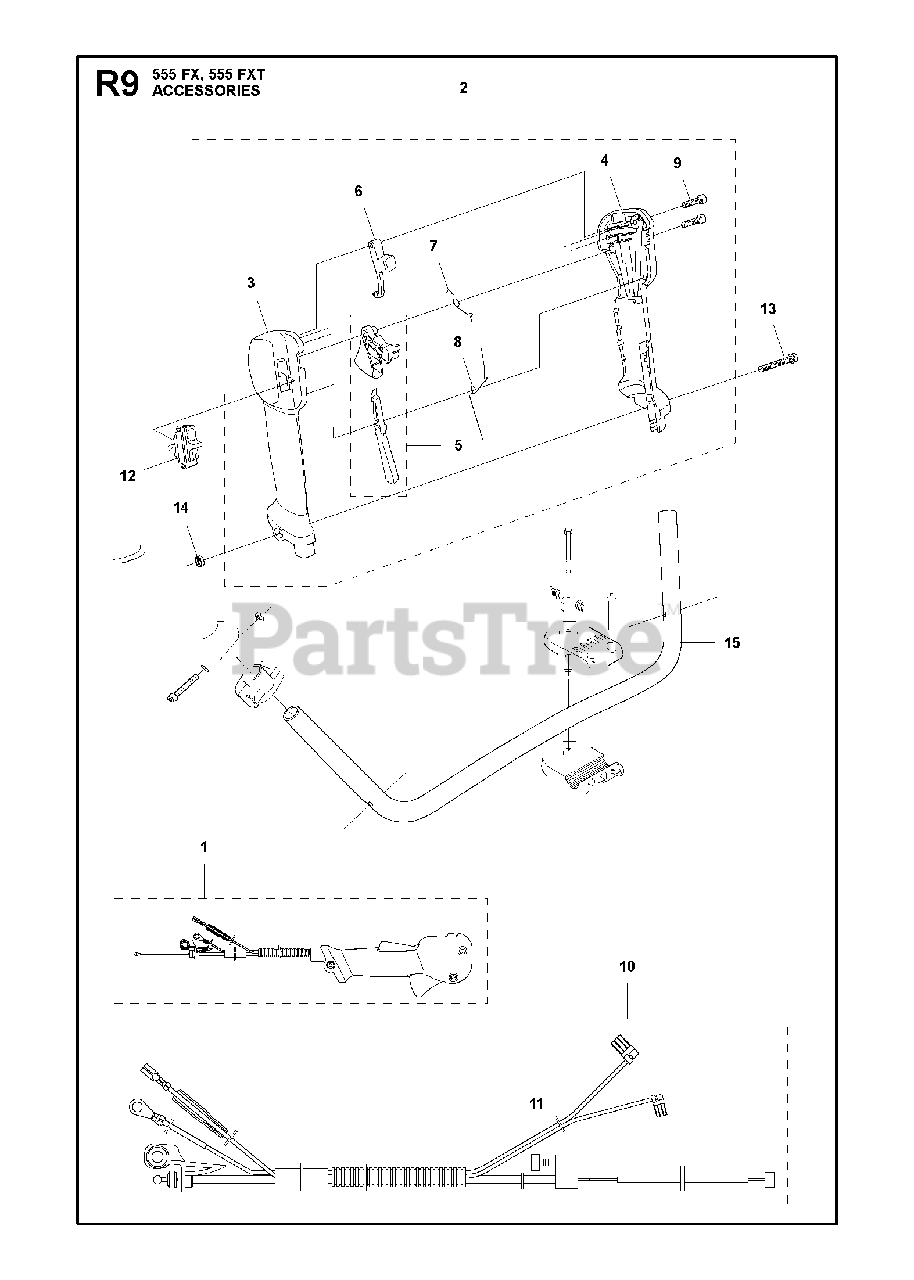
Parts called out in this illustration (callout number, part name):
1	Throttle Handle Assembly
2	THROTTLE HANDLE ASSY
3	HANDLE HALF LEFT
4	HANDLE HALF RIGHT
5	THROTTLE CONTROL
6	LOCKOUT STARTER THROTTLE
7	SPRING
8	SPRING
9	SCREW IHSCT MT4X18 10.9 ZN/FE
10	WIRING ASSY SKOG
11	SCREW
12	STOP BUTTON
13	SCREW IHSCFM
